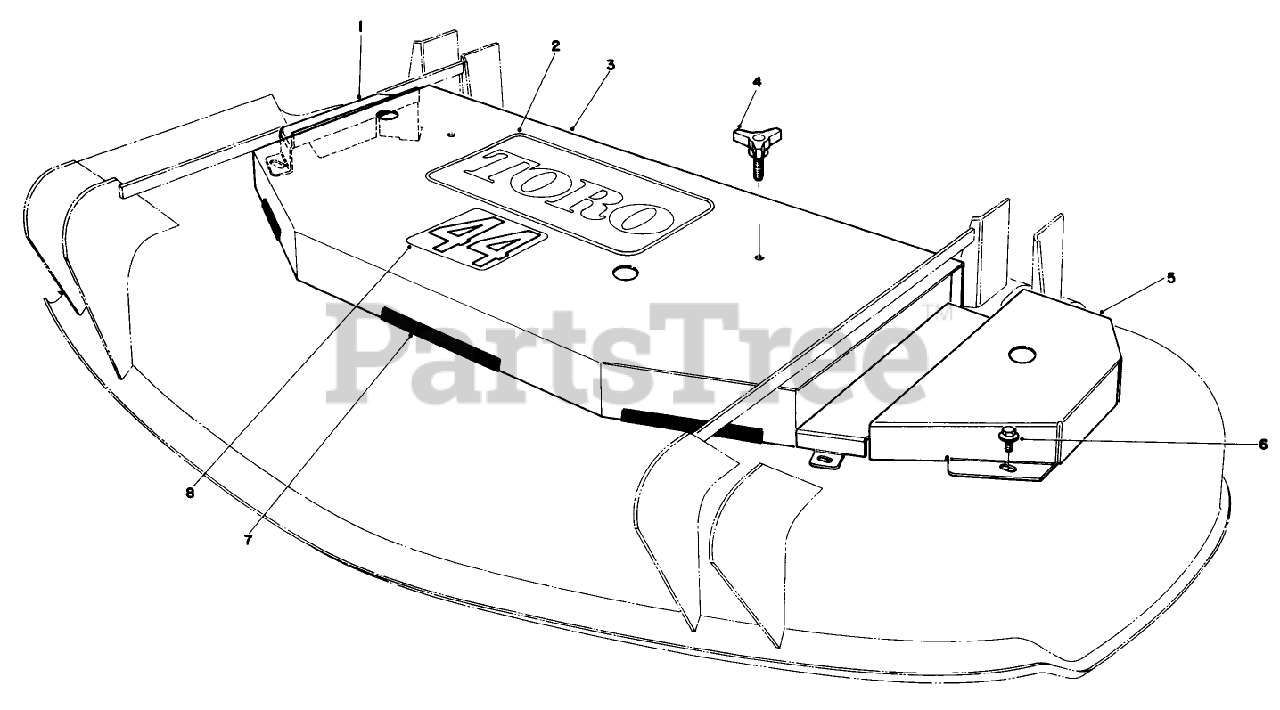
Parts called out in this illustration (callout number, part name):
2	DECAL
6	SCREW-HHFTF
7	TRIM-JIFFY
8	DECAL-44 INCH
